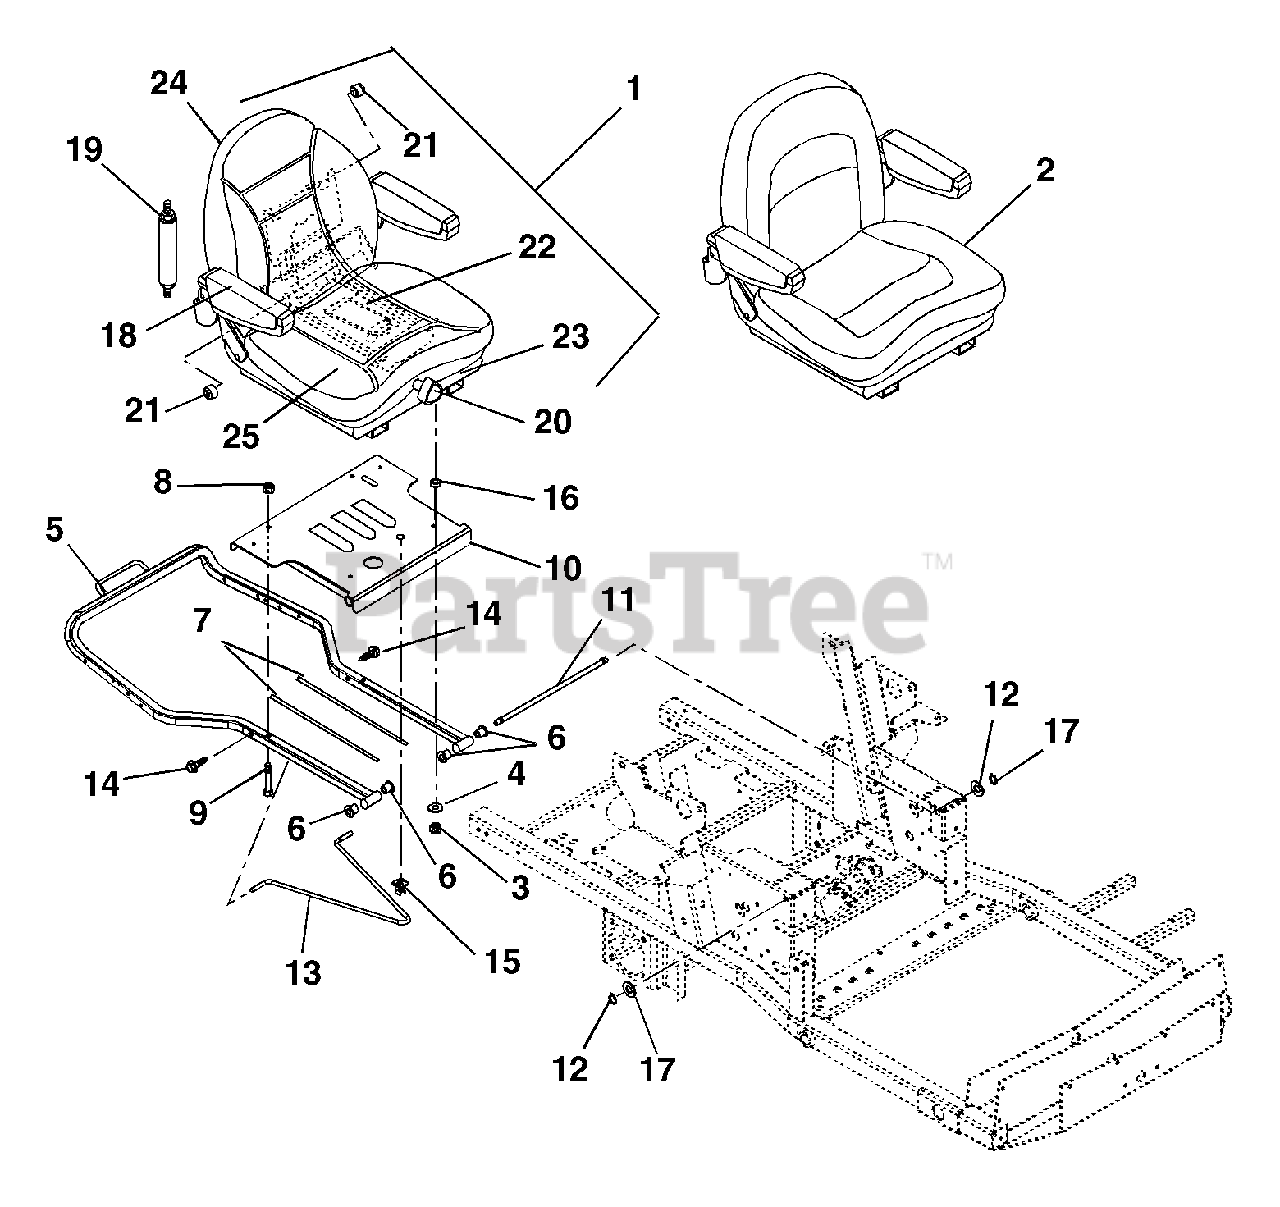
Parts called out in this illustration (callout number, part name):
1	Seat-Suspension (020, 029, 030, 032, 033, 035)
2	Seat\ (034)
3	Nut-Locking-Nylon M8-1.25 (020, 029, 030, 032, 033, 035)
3	Nut-Locking-Nylon .312-18 (034)
4	Washer-Flat-Steel .38 x .875 x .083
5	Weldment- Hood Frame
6	Bushing-Flange .515 x .750 x .745 x 1.00
7	Tape -VHB 4941F
8	Nut-Locking-Top-Flange .38-16
9	Bolt-Rib Neck .38-16 x 1.50
10	Weldment-Seat Pivot Plate
11	Rod-Seat Frame Pivot
12	Ring-Retaining-External .500 x .050
13	Rod-Prop
14	Screw-Tapping .25-20 x .50 Hex Washer Head (020, 029, 030, 032, 033, 035)
16	Bushing-Sleeve .377 x .624 x .235
17	Washer-Flat-Steel .531 x 1.06 x .095
18	Kit-Arm Pad (1 per bag)
19	Kit-Damper w/Hardware (020, 029, 030, 032, 033, 035)
20	Kit-Knob (1 per bag)
21	Kit-Roller (4 per bag)
22	Kit-Spring Cable (1 per bag)
23	Kit-Adjuster (1 per carton)
24	Kit-Seatback (020, 029, 030, 032, 033, 035)
25	Kit-Cushion (1 per carton)
